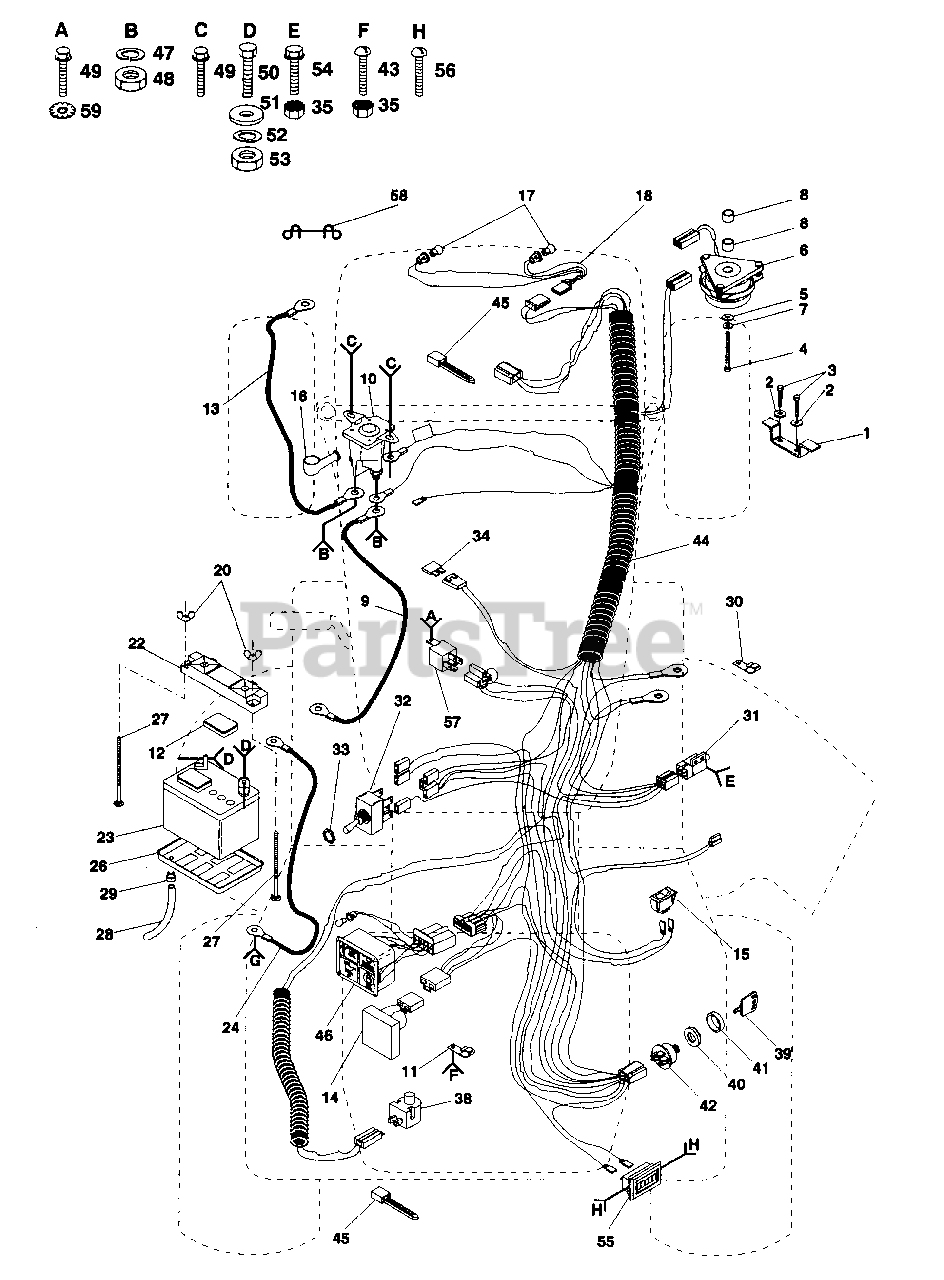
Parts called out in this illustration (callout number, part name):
1	Stop, Clutch (AYP part number)
2	Washer, Lock 3/8 (AYP part number)
3	Bolt, Hex 3/8-16 x 3/4 (AYP part number)
4	Bolt, Hex 7/16-20 x 1-1/2 Gr. 5
5	Washer (AYP part number)
6	Clutch, Electric (AYP part number)
7	Washer, Lock 7/16 (AYP part number)
8	Spacer, Clutch (AYP part number)
9	Cable, Battery (AYP part number)
10	Solenoid (AYP part number)
11	Clip, Insulated (AYP part number)
12	Battery, Caps (AYP part number)
13	Cable, Starter (AYP part number)
14	Sensor, Low Voltage (AYP part number)
15	Switch, Light (AYP part number)
16	Cover, Terminal (AYP part number)
17	Bulb, Light (AYP part number)
18	Harness, Light Socket (AYP part number)
19	Bulb, Light Package (AYP part number)
20	Nut, Wing 1/4-20 (AYP part number)
22	Guard, Terminal (AYP part number)
23	Battery (AYP part number)
24	Cable, Ground (AYP part number)
26	Tray, Battery (AYP part number)
27	Bolt, Carriage 1/4-20 x 7-1/2 (AYP part number)
28	Tube, Plastic (AYP part number)
29	Clamp, Hose (AYP part number)
30	Clip (AYP part number)
31	Switch, Interlock (AYP part number)
32	Switch, P.T.O.
33	Nut, Hex (AYP part number)
34	Fuse (AYP part number)
35	Nut, Keps #10-32 (AYP part number)
38	Switch, Seat (AYP part number)
39	Key (AYP part number)
40	Nut, Ignition (AYP part number)
41	Bezel, Ignition (AYP part number)
42	Switch, Ignition (AYP part number)
43	Screw, Slot, Pan Head #10-33 x 1/2 (AYP part number)
44	Harness, Ignition (AYP part number)
45	Cable, Tie (AYP part number)
46	Light Package (AYP part number)
47	Washer, Lock 1/4 (AYP part number)
48	Nut, Hex Jam 1/4-20 (AYP part number)
49	Screw, Hex Washer Hd. Cutting 1/4-20 x 1/2 (AYP part number)
50	Bolt, Hex Hd. 1/4-20 x 3/4 (AYP part number)
51	Washer 9/32 x 5/8 x 16 Gauge (AYP part number)
52	Washer, Lock 1/4 (AYP part number)
53	Nut, Hex 1/4-20 (AYP part number)
54	Screw, Hex Washer Hd. #10-32 x 1-1/2 (AYP part number)
55	Meter, Hour (AYP part number)
56	Screw #10-24 x 1/2 (Black) (AYP part number)
57	Assembly, Relay (AYP part number)
59	Washer, Lock External Tooth 3/8 (AYP part number)
